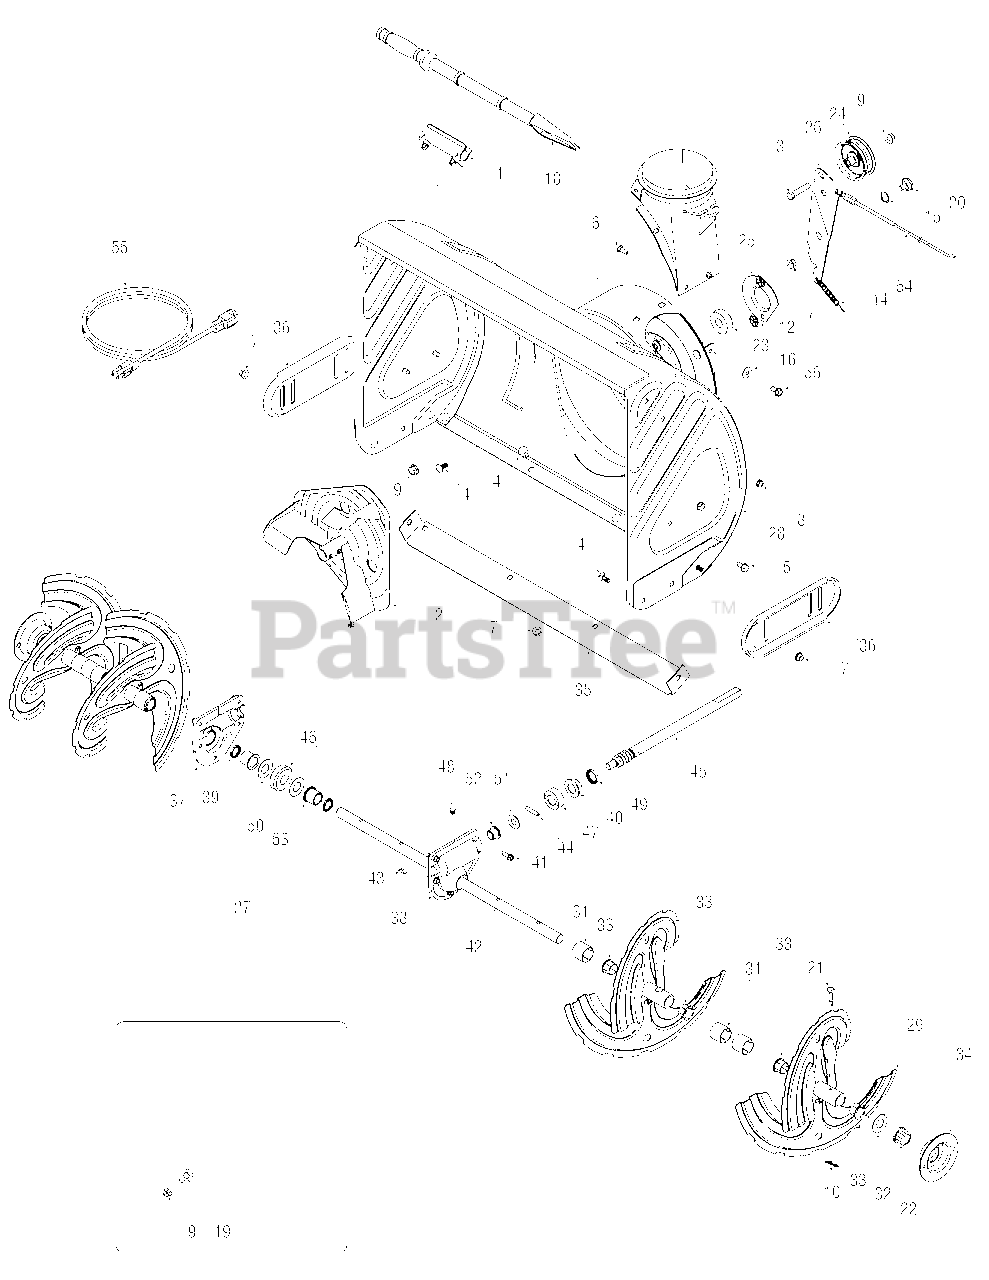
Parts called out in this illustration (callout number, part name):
1	Snow Removal Tool Mount
3	Hex Screw, 3/8-16, 1.75, Gr5
4	Bolt, Carriage, 5/16-18, .750 Gr1
5	Screw, 5/16-18, 0.625
6	Screw, Carriage, 1/4-20, .750, Gr5
7	Nut, Flange Lock, 5/16-18, Nylon
8	Nut, Flange Lock, 1/4-20, Nylon
9	Nut, Flange Lock, 3/8-16, Nylon
10	Cotter Pin, Bow-tie
11	Cable, Tie, 3/16 x .05 x 7.4
12	Nut, Push-on, .25 Dia
13	Chute, Adapter 5" Dia
14	Spring, Extension, .38 OD x 3.6
15	Washer, Wave, .625 x .885 x .015
16	Washer, Bell, .340 x .872 x .060
17	Washer, Flat, .25 x .630 x .0515
18	Snow Removal Tool
19	Screw, Shoulder, .498 x .34, 3/8-16
20	Screw, Shoulder, .625 x .17, 3/8-16
21	Shear Pin, .25 x 1.50
22	Bearing, Hex Flange x .75 ID
23	Bearing, Ball, .75 ID x 1.85 OD
24	Flat Pulley, Idler, 2.75 OD
25	Housing, Bearing, 1.85 ID
27	Gearbox Assembly, Auger, 28"
31	Spacer, 1.25 OD x .75 ID x 1.00
32	Washer, Flat, .76 x 1.49 x .06
33	Bushing, Flange, .80 ID x .91 OD
37	Housing, Auger, RH Reducer
38	Housing, Auger, LH Reducer
39	Seal, Oil, .750 ID
40	Bearing, Flange, .75 x 1.0 x .59
41	Screw, Self-tapping, 1/4-20, 0.750
42	Axle, Auger, 28"
43	Key, Hi-pro 3/16 x 5/8
44	Pin, Dowel, .25 OD x 1.2
45	Shaft, Worm .75 OD
46	Gear, Worm 20T
47	Collar, Thrust
48	Plug, 1/4 x .437
49	Seal, Oil, .75 x 1 x .131
50	Washer, Flat, .760 ID x 1.5 OD
51	Washer, Flat, .51 x 1.12
52	Bearing, Flange, .75 x 1.0 x .925
53	Bearing, Flange, .75 x 1.00 x .975
54	Clutch Cable, Auger, 47.23"
55	Extention Cord, 110V
56	Screw, 5/16-18, 0.75
